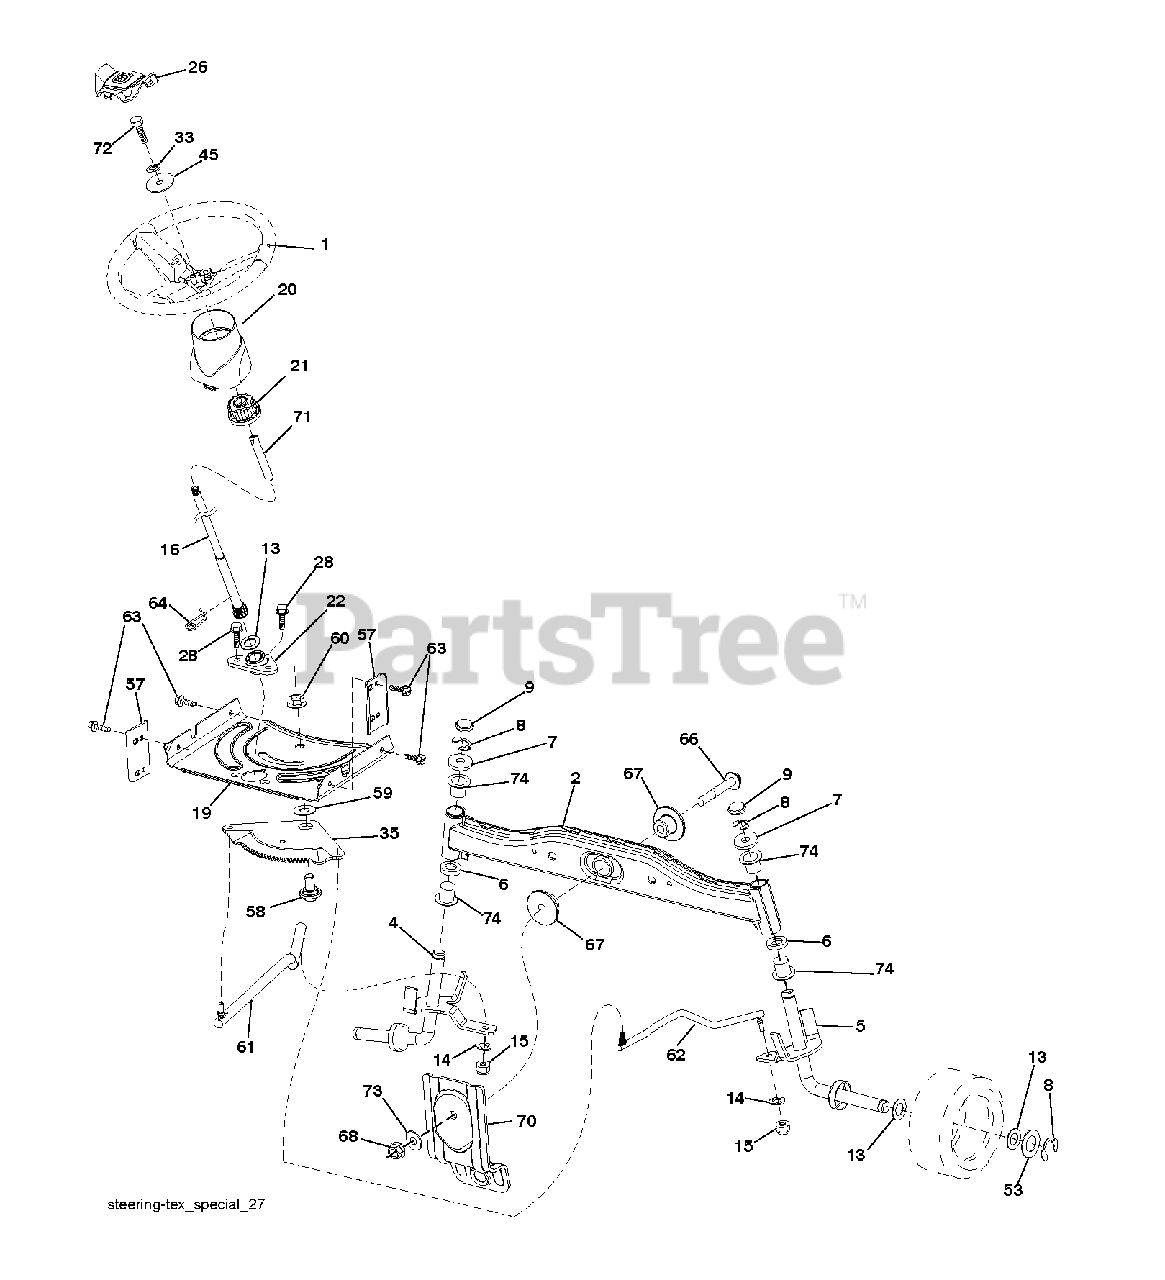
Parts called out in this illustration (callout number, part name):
1	WHEEL.STEERING.STDSRR.BLK/OV
2	AXLE HALF ASM-WELDED
4	SPINDLE.WELDED.LH.15"TEX
5	SPINDLE.WELDED.RH.15"T
8	RING CLIP
9	CAP.SPINDLE
14	WASHER, LOCK 3/8
15	NUT CROWNLOCK 3/8-24
16	SHAFT STEERING
19	PLATE.STEER.DDL.NLT/NG
20	BOOT.STEERING.PREDATOR.LT.BLAC
21	ADAPTER, WHEEL STNG..
22	BUSHING.ASM.STEERING.A
26	CAP.WHL.STRNG.STDSRRD.SRS.BLK
28	SCREW, 3/8-16X3/4
33	LOCKWASHER
35	GEAR.SECTOR.PLATE.DDL.
45	WASHER.11/32
53	WASHER.HARDENED
57	BRACKET.UPSTOP.TEX
58	BOLT.SHOULDER.SECTOR.P
59	WASHER.THURST.SECTOR.S
60	NUT FLANGE LOCK 5/8-11
61	DRAGLINK.LH.BALLSTUD.D
62	DRAGLINK.RH.BALLSTUD.D
63	SCREW
64	RETAINER.CLIP.SPRING.S
66	BOLT HEX FGHD 7/16-14 X 3 SERR
67	BUSHING.PM.FRONT AXLE
68	NUT.LOCK.FLANGE.7/16
70	BRKT.DECK.SUSPENSION.F
71	SHAFT EXTENSION STEERING
72	BOLT YT
73	WASHER.1.5X.505X.118
74	BRNG T
